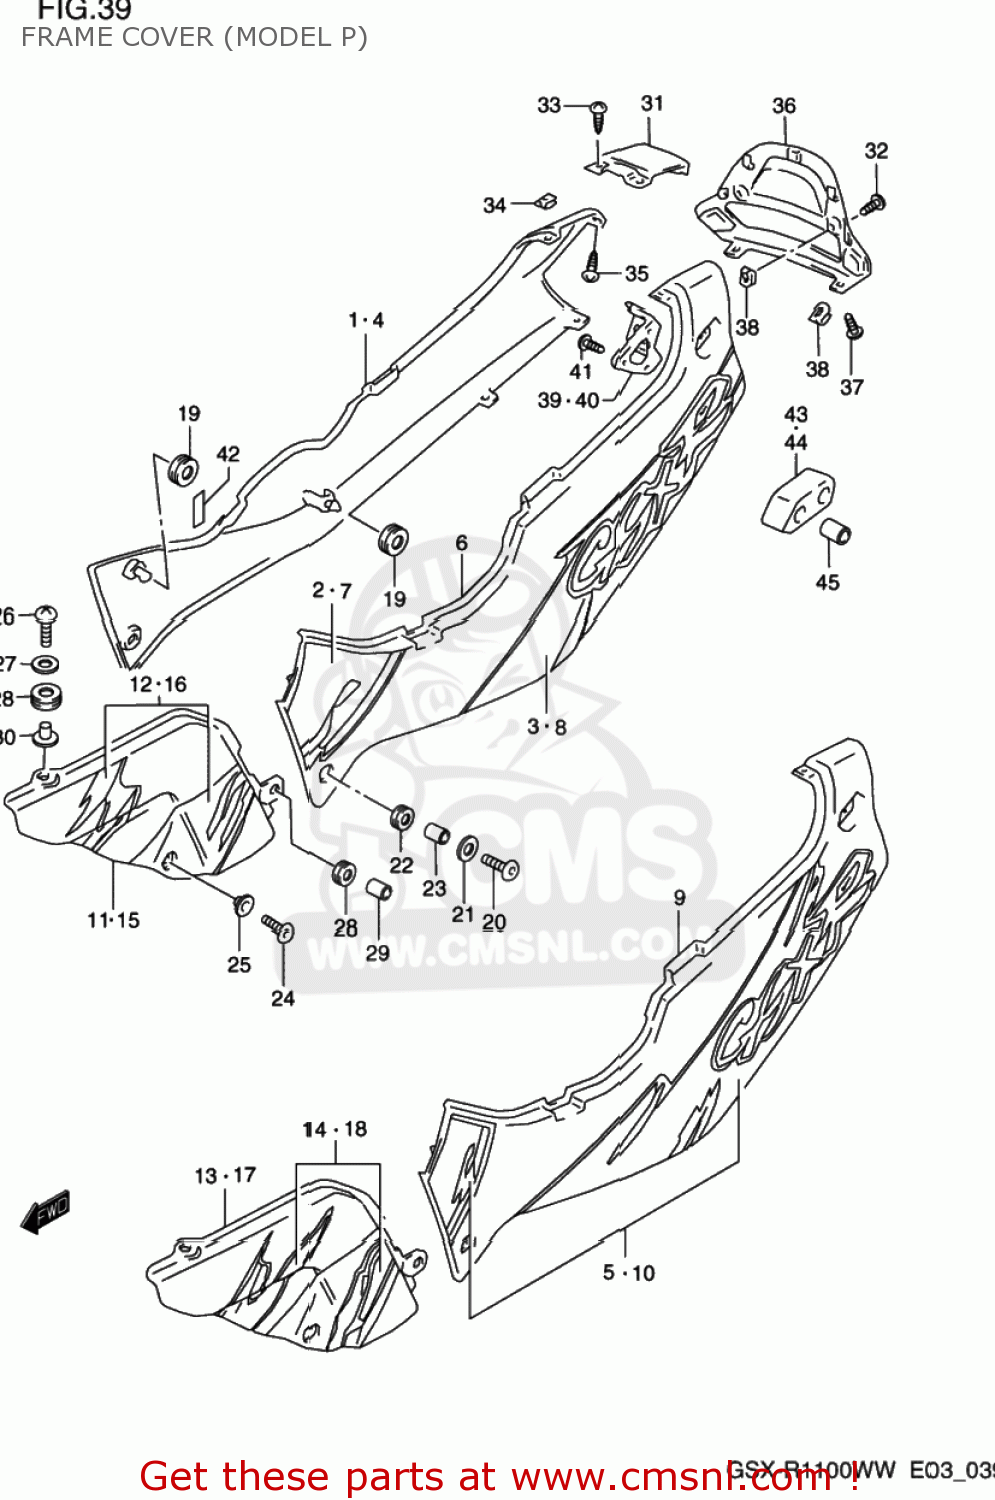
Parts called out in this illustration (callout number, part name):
1	COVER ASSEMBLY,FRAME,RIGHT
2	TAPE,FRAME COVER UPR,R
3	TAPE,FRAME COVER LWR,R
4	COVER ASSEMBLY,FRAME,RIGHT
5	TAPE SET,FRAME COVER,RIGHT
6	COVER ASSEMBLY,FRAME,LEFT
7	TAPE,FRAME COVER UPR,L
8	TAPE,FRAME COVER LWR,L
9	COVER ASSY,FRAME(BLACK)
10	TAPE SET,FRAME COVER,L
11	COVER,FRAME BODY,RIGHT
12	TAPE SET,FRAME COVER B
13	COVER ASSEMBLY,FRAME BODY
14	TAPE SET,FRAME COVER B
15	COVER,FRAME BODY,L
16	TAPE SET,FRAME COVER B
17	COVER ASSEMBLY,FRAME BODY
18	TAPE SET,FRAME COVER BODY,L
19	CUSHION
20	SCREW(6X30)
21	WASHER
22	CUSHION
23	SPACER (6.1X9X9)
24	SCREW(5X14)
25	WASHER
26	SCREW(6X25)
27	WASHER (6.5X18X1.6)
28	CUSHION
29	SPACER (6.1X9X9)
30	WASHER
31	COVER ASSY,FRAME CTR
32	SCREW(5X12)
33	SCREW
34	NUT
35	SCREW
36	COVER,FRAME RR
37	SCREW(5X12)
38	NUT
39	BRACKET,RR COMBINATION LAMP,L
40	BRACKET,RR COMBINATION LAMP,L
41	SCREW
42	CUSHION
43	CUSHION,PILLION RIDER HANDLE,R
44	CUSHION,PILLION RIDER HANDLE,L
45	SPACER (8.5X16X37)
